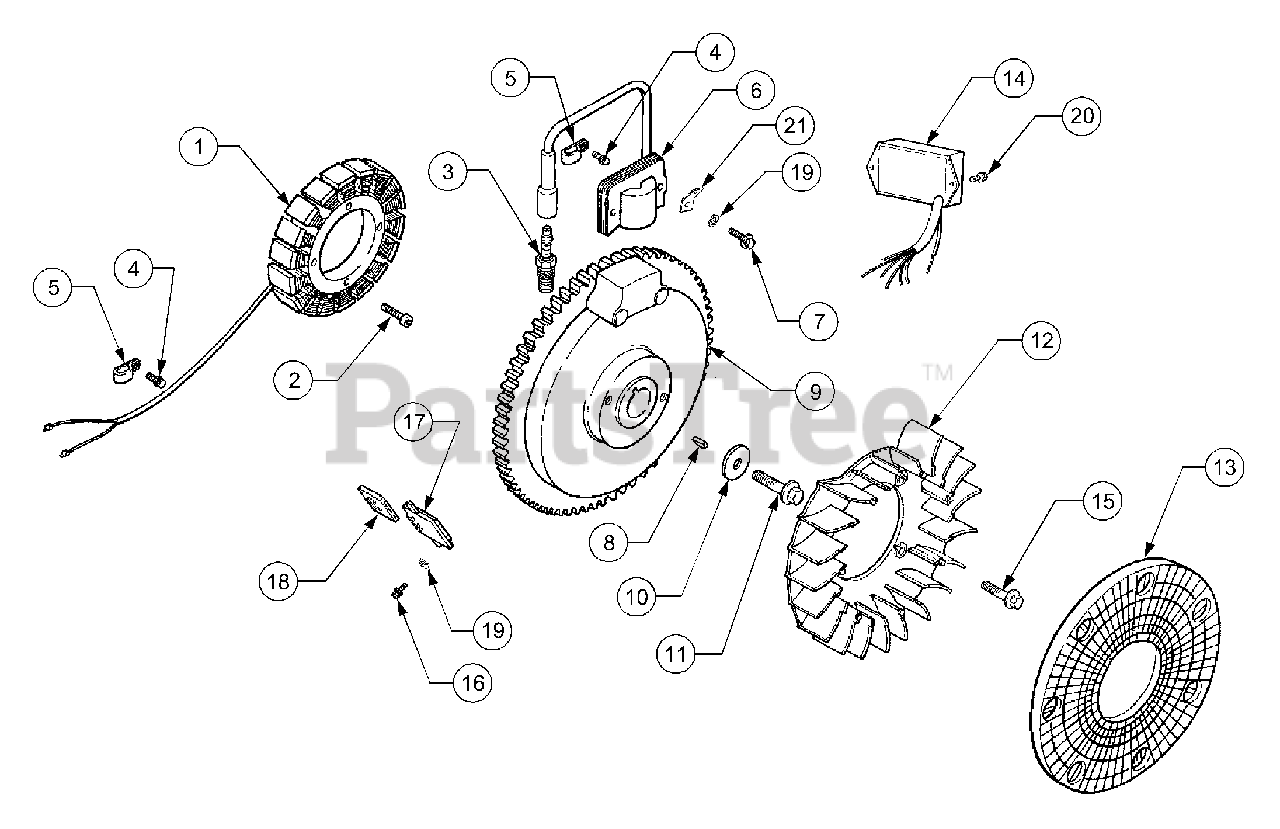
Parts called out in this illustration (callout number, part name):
1	Kit, Stator,
2	Screw, Stator Mntg, M5 x 0.8 x 25
3	Spark Plug
4	Screw, Harness Clip, M5 x .8 x 10
5	Clip, Cable
6	Module, Ignition
7	Screw, Ign Module, M4 x .7 x 4.0
10	Washer, Flywheel
11	Screw, Flywheel, M10 x 1.5 x 46
12	Fan
13	Screen, Grass
14	Module, Digital Speed Advance
15	Bolt, Shoulder M6 x 1 x 16
16	Screw, Phillips Hd. 11-16 x 7/8
17	Rectifier-Regulator
18	Connector, Three Contact
19	Washer, Lock, 1/4
20	Screw, Pan Head, M4.2 x 13
